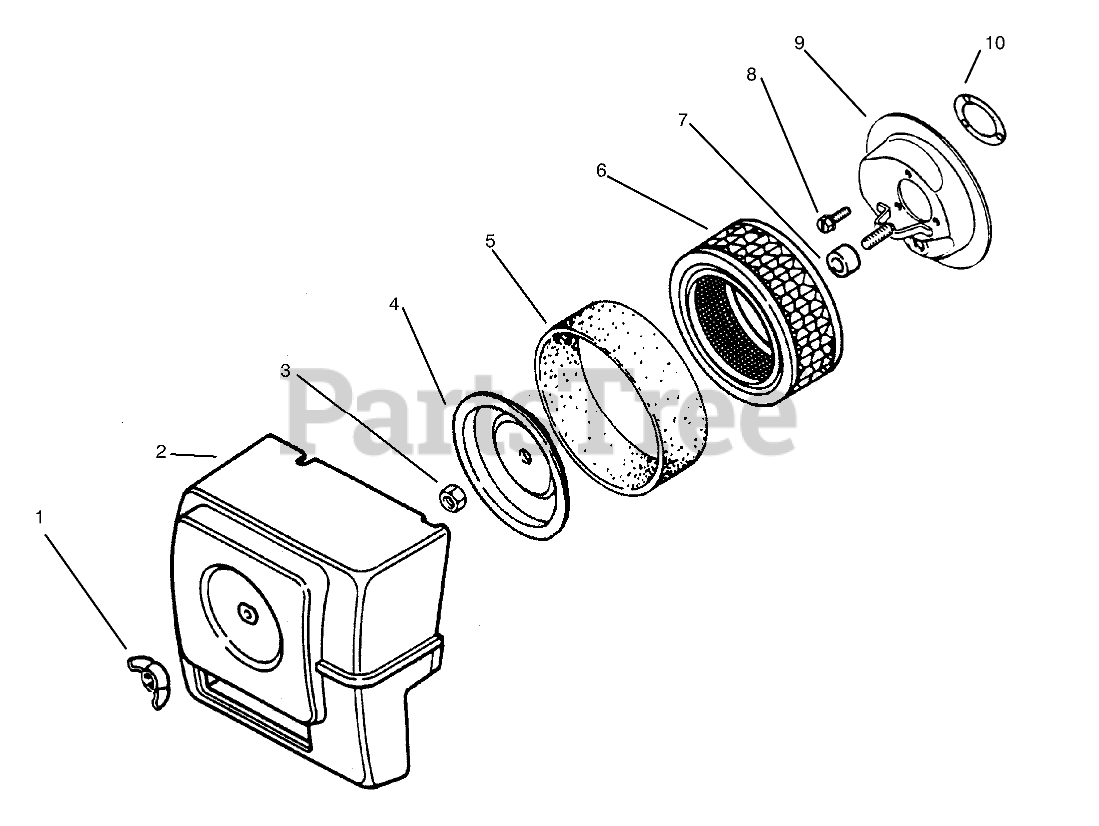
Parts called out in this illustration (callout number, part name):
1	Nut-Wing
4	Cover-Air Clean Element
5	Precleaner
6	Element
7	Seal
8	Screw
9	Base-Air Cleaner
